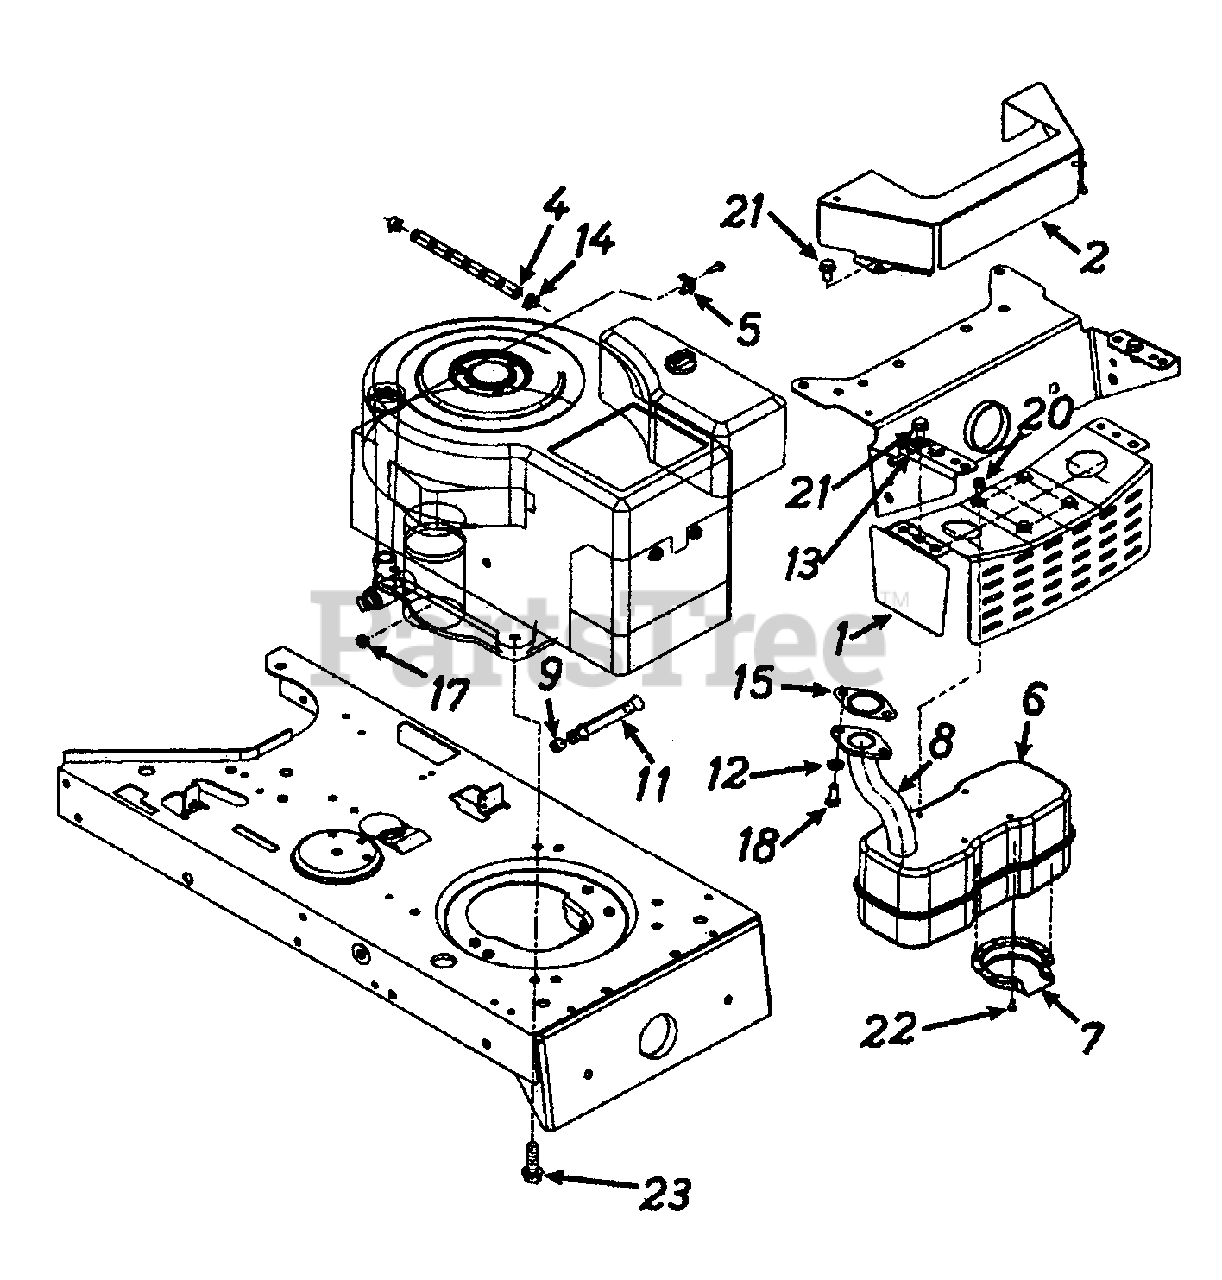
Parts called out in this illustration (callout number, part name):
1	Heat Shield Bracket
4	Fuel Line
5	Casing Clamp
6	Muffler
7	Muffler Deflector
8	Exhaust Pipe
9	Hex Pipe Plug
11	Pipe 3/8 NPT x 3.8" Lg.
12	L-Wash. 5/16" I.D.
13	Clamp
14	Hose Clamp
15	Exhaust Gasket
17	Hex Sems Nut 1/4-20 Thd.
18	Socket Hd. Bolt 5/16-18 x .62" Lg.
21	Hex Wash. Hd. TT-Scr. 5/16-18 x .62" Lg.
22	Hex Bolt #8-32 x .38" Lg.
23	Hex Wash. Hd. TT-Scr. 3/8-16 x 1.25" Lg.
